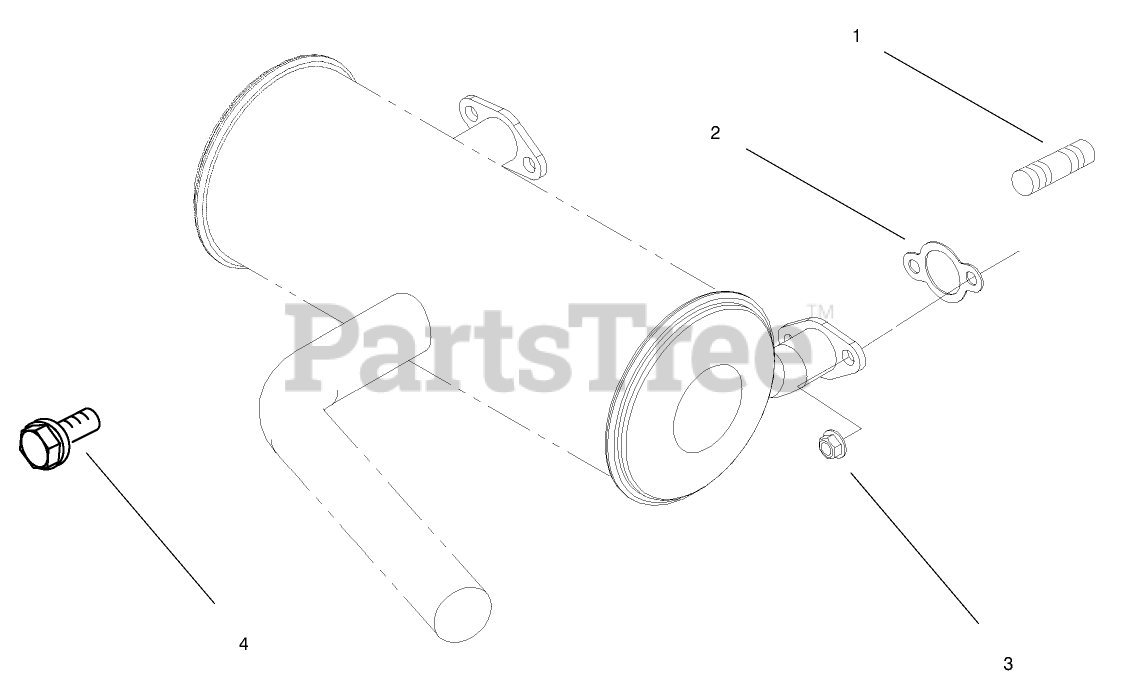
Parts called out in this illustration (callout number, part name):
1	Stud
2	GASKET-EXHAUST
3	Nut
4	Screw, tank bracket - starter end
